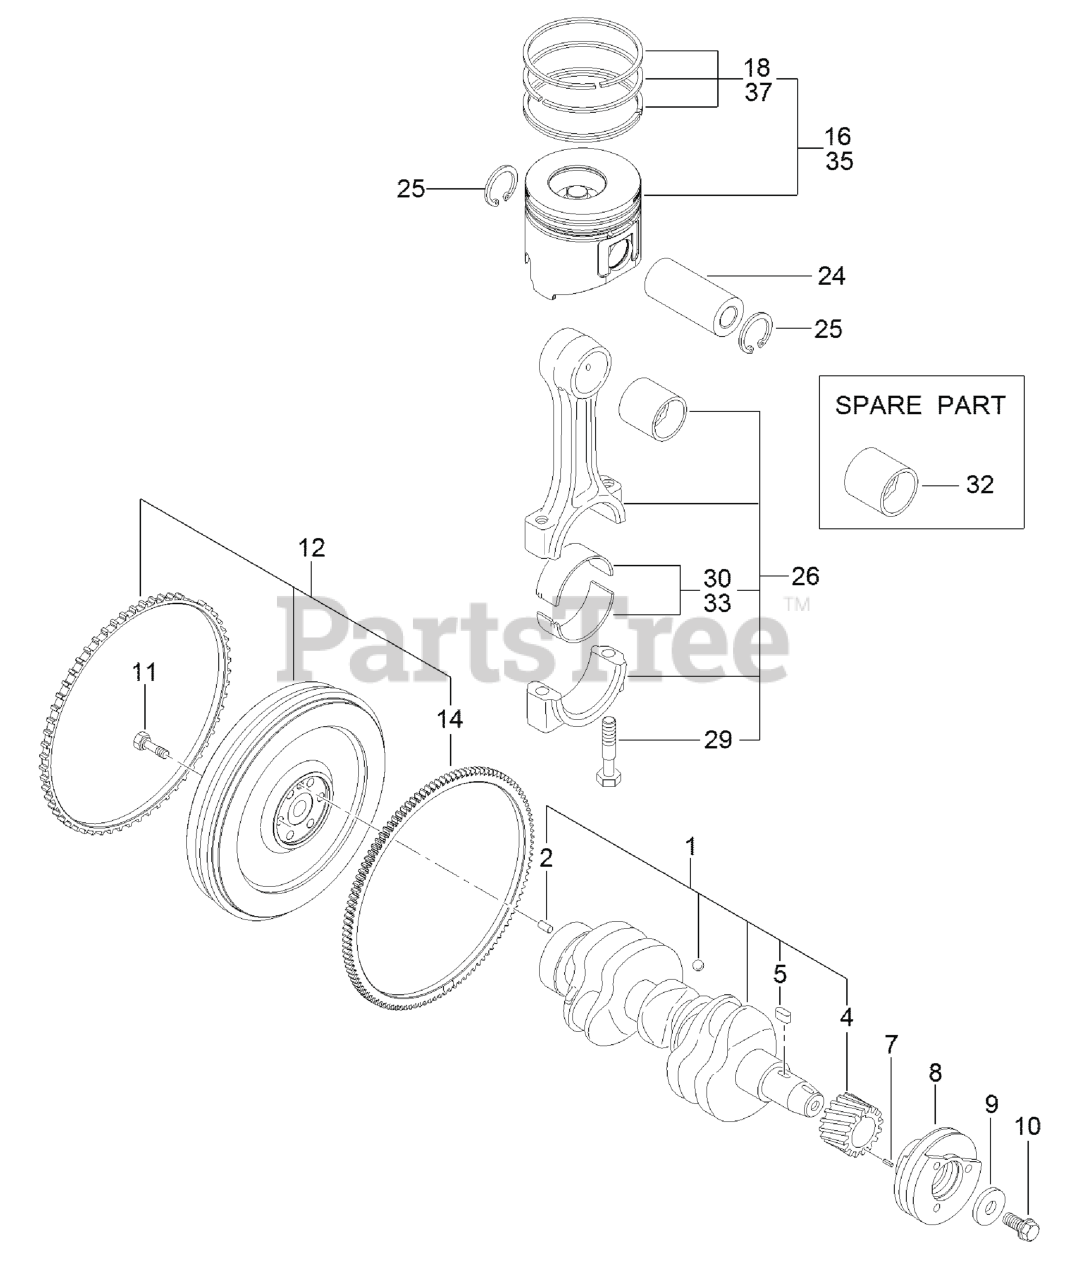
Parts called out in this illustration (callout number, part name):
1	CRANKSHAFT ASM
7	PIN-SPRING
8	PULLEY-V
12	FLYWHEEL ASM
16	PISTON ASM
18	PISTON RING ASM
26	CONNECTING ROD ASM
30	PIN-CRANK
32	PIN-PISTON
33	PIN-CRANK (.25)
35	PISTON ASM (0.25 O S)
37	RING SET (0.25 O S)
